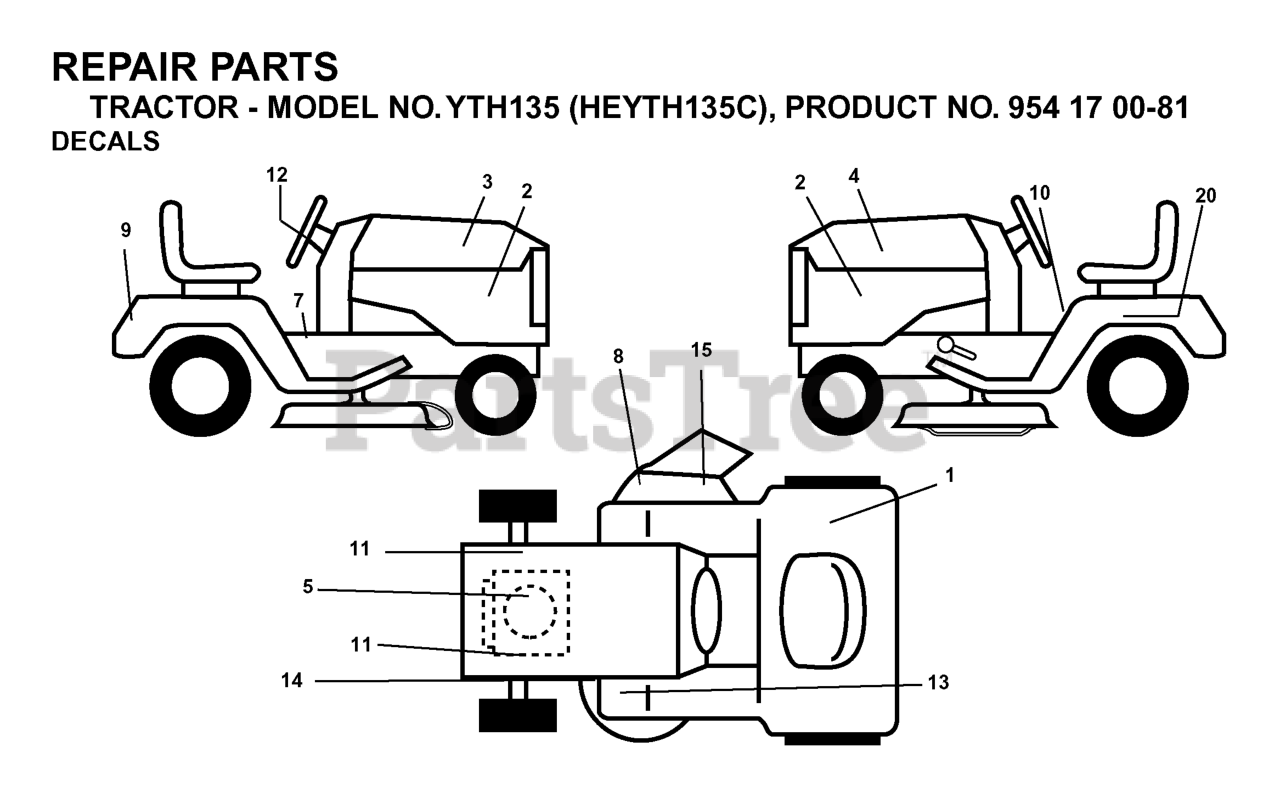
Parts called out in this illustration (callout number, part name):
1	Decal, Fender 100 DB/CE
2	DECAL PNL SIDE
7	DECAL PARK BRAKE
8	DECAL.INTERNATIONL.CUTFINGER
9	DECAL FENDER HUSQ
10	DECAL READ OWNER'S MAN SYMS
12	DECAL.WHEEL.STEERING.HUSQ.PERM
13	DECAL
14	DECAL V BELT SCHEMATIC
15	DECAL DECK "B" 42"
20	DECAL BTRY SYMBOLS
